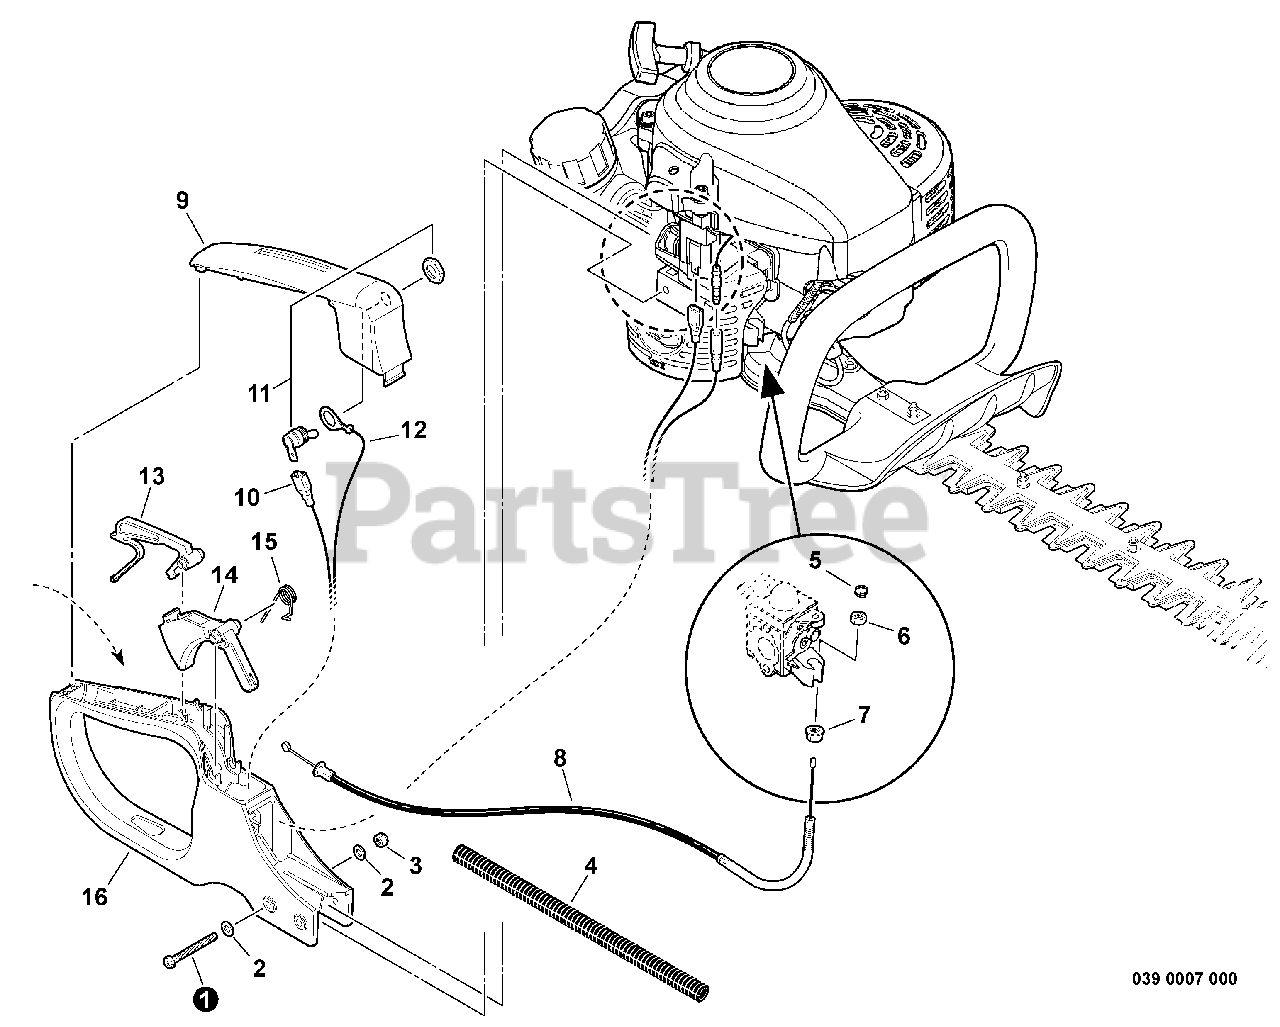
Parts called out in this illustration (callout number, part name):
1	SCREW - 5X45
2	WASHER - 5
3	LOCKNUT - 5
4	TUBE, PROTECTIVE - CORRUGATED
7	NUT - 6 -- FLANGE
8	CABLE, THROTTLE
9	COVER, HANDLE
10	LEAD - IGNITION
11	IGNITION SWITCH ASSY
12	LEAD - GROUND
13	LEVER, TRIGGER LOCKOUT
14	TRIGGER, THROTTLE
15	SPRING, TRIGGER
16	HANDLE - REAR
